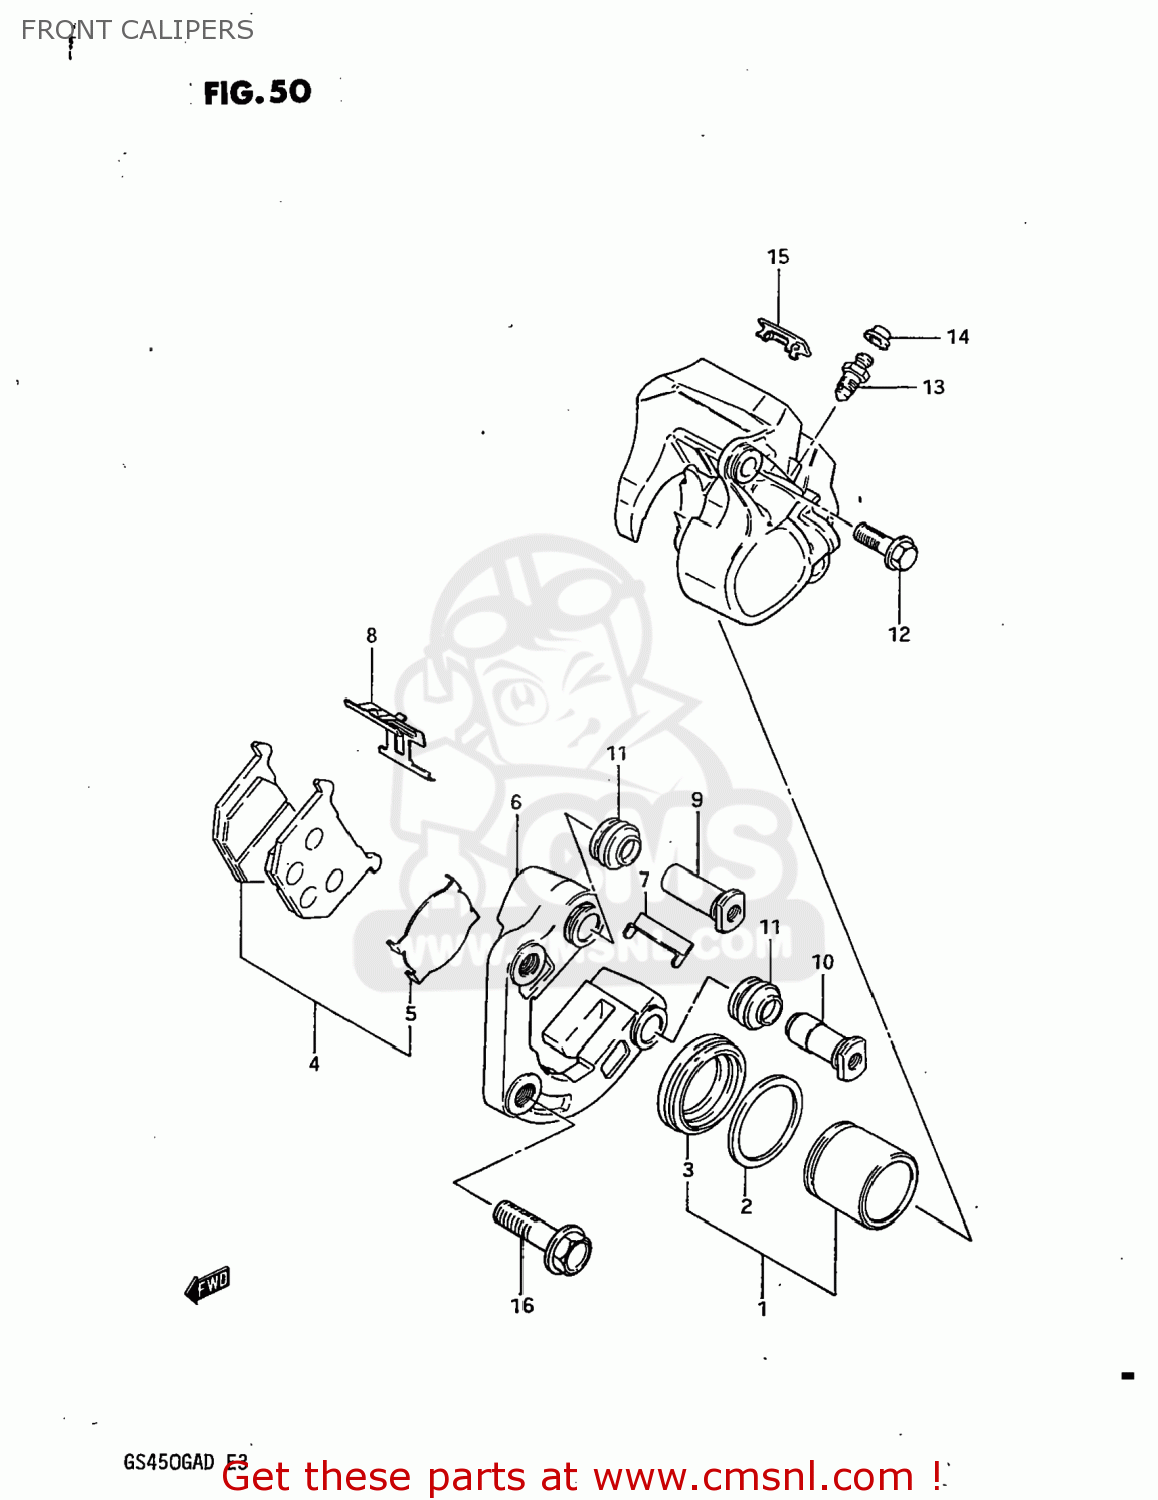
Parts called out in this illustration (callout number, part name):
1	PISTON SET
2	SEAL,FR CALIPE
3	BOOT,PISTON
4	PAD SET,BRAKE (MCA)
5	SHIM,PAD
6	CARRIER,CALIPER,LEFT
7	GUIDE,PAD
8	SPRING,PAD
9	AXLE NO.1
10	AXLE NO.2
11	BOOT,AXLE
12	BOLT
13	BLEEDER
14	CAP,BREATHER
15	COVER
16	BOLT(10X37)
